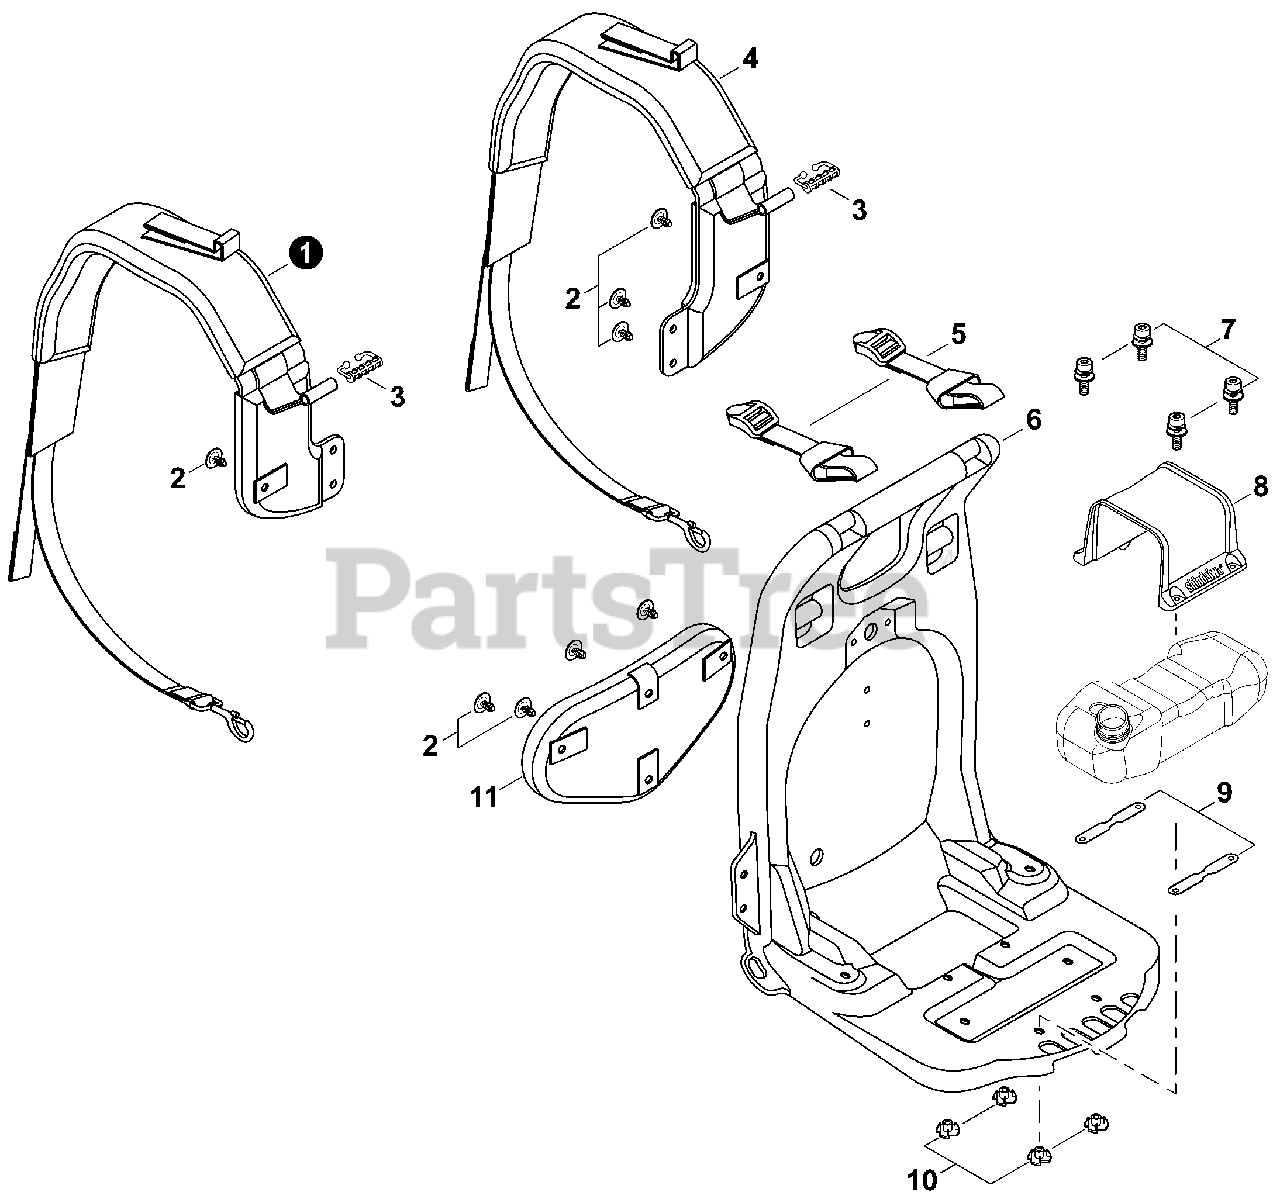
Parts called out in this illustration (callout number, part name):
1	HARNESS ASSY, LEFT
3	CLIP, HARNESS
4	HARNESS ASSY, RIGHT
5	STRAP, HARNESS
6	FRAME, BACKPACK
7	BOLT M5×16
8	RETAINER, FUEL TANK
10	T-NUT M5
11	PAD, BACKPACK
